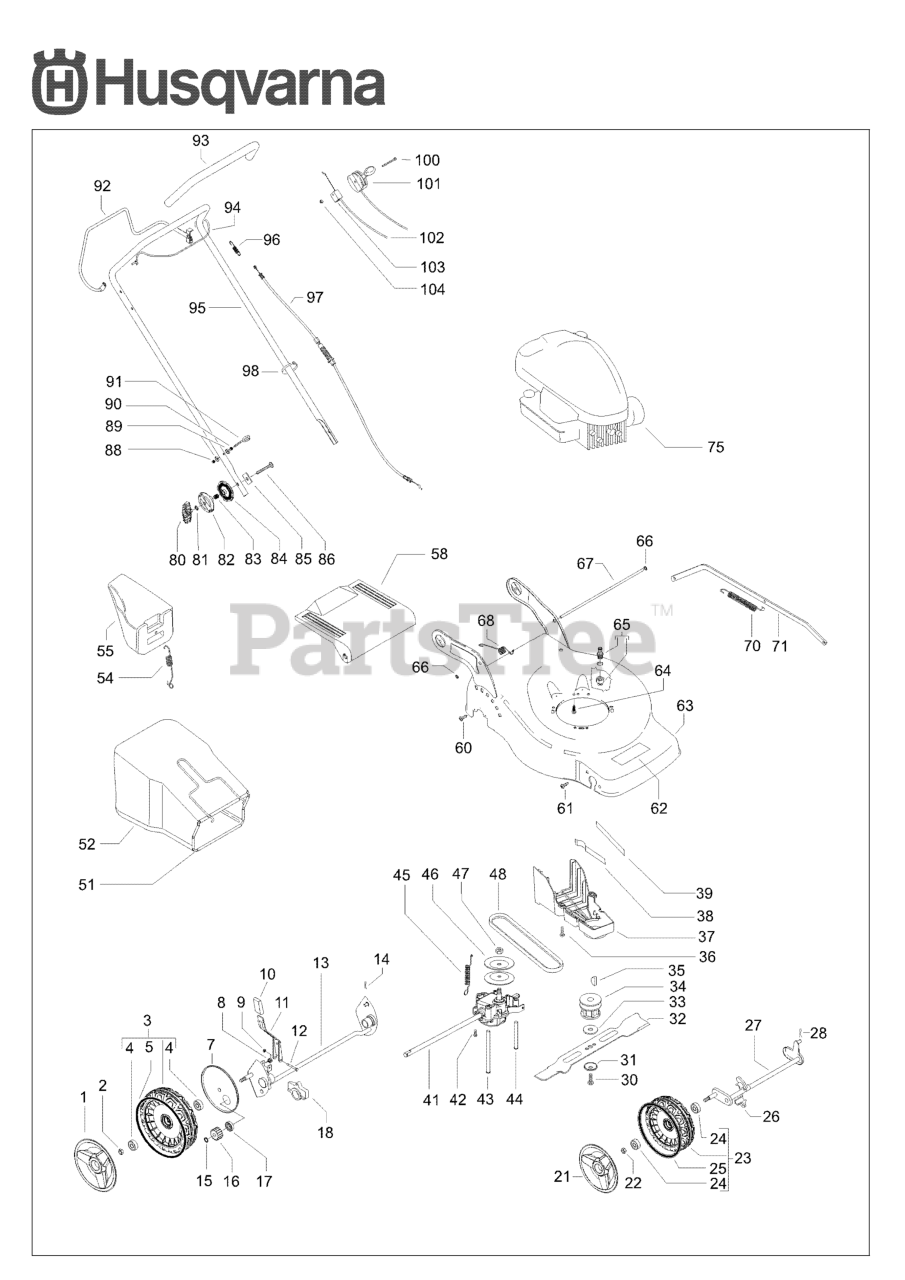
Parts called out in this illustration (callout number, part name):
1	DIFF, FRONT AUTO CCW 102371801
2	KIT, ASSY, OUTPUT COVER PLATE
3	SET SCREW, #10-24 UNC-3A, PATC
4	THRUST BUTTON
5	THRUST PLATE
14	KIT, ASSY, RACE OUTPUT HUB
15	DOWEL PIN, 1/2" DIA X 1" LG
16	BEARING, NRT, TC815
20	KIT, ASSY, CLUTCH
21	CLUTCH HSG/RING GEAR, MACHINED
22	KIT, ROLL
23	KIT, ASSY, ROLL CAGE
26	KIT, BOLT
27	KIT, MINOR REPAIR
32	RETAINING, RING INTERNAL
33	ARMATURE PLATE
34	SHIM, ARMATURE, PLATE
35	BEARING, DGBR, 6008-C3
36	KIT, ASSY, DRAIN PLUG
39	PLUG, OIL FILL
